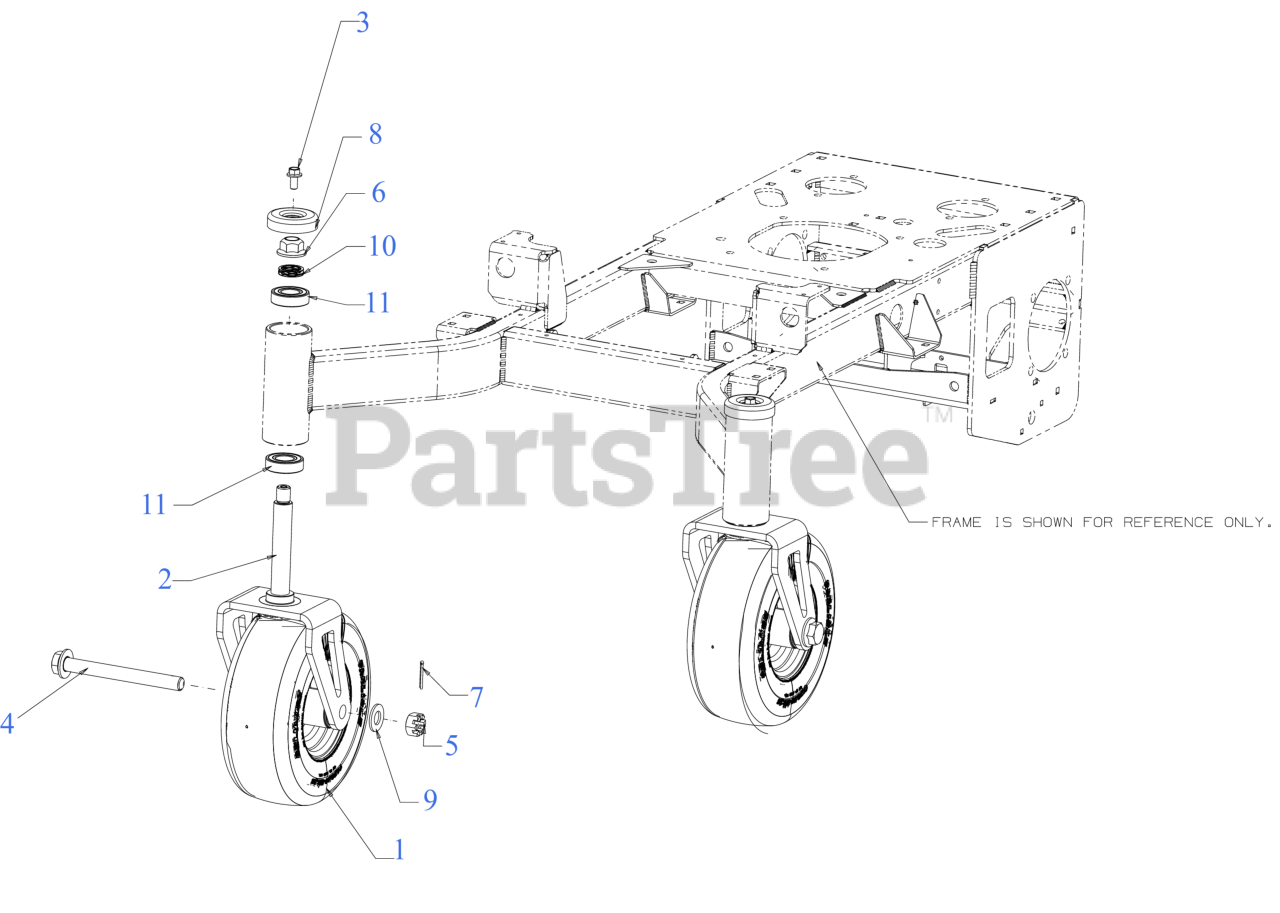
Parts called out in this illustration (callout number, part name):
1	WHEEL ASSEMBLY (11 x 4 - 5 SIMI PNE)
2	CASTER YOKE
3	BOLT - 3/8-16:.75:GR5:PATCH LOCK
4	HEX FLANGE BOLT 3/4-16x7.0 GR5
5	HEX NUT CASTLE 3/4-16
6	FLANGE LOCK NUT 3/4-16 TOP LOCK
7	COTTER PIN-5/32 DIA
8	AXLE CAP 2.5"
9	FLAT WASHER
10	WAVE WASHER
11	BALL BEARING (1.0 x 52 x 15)
